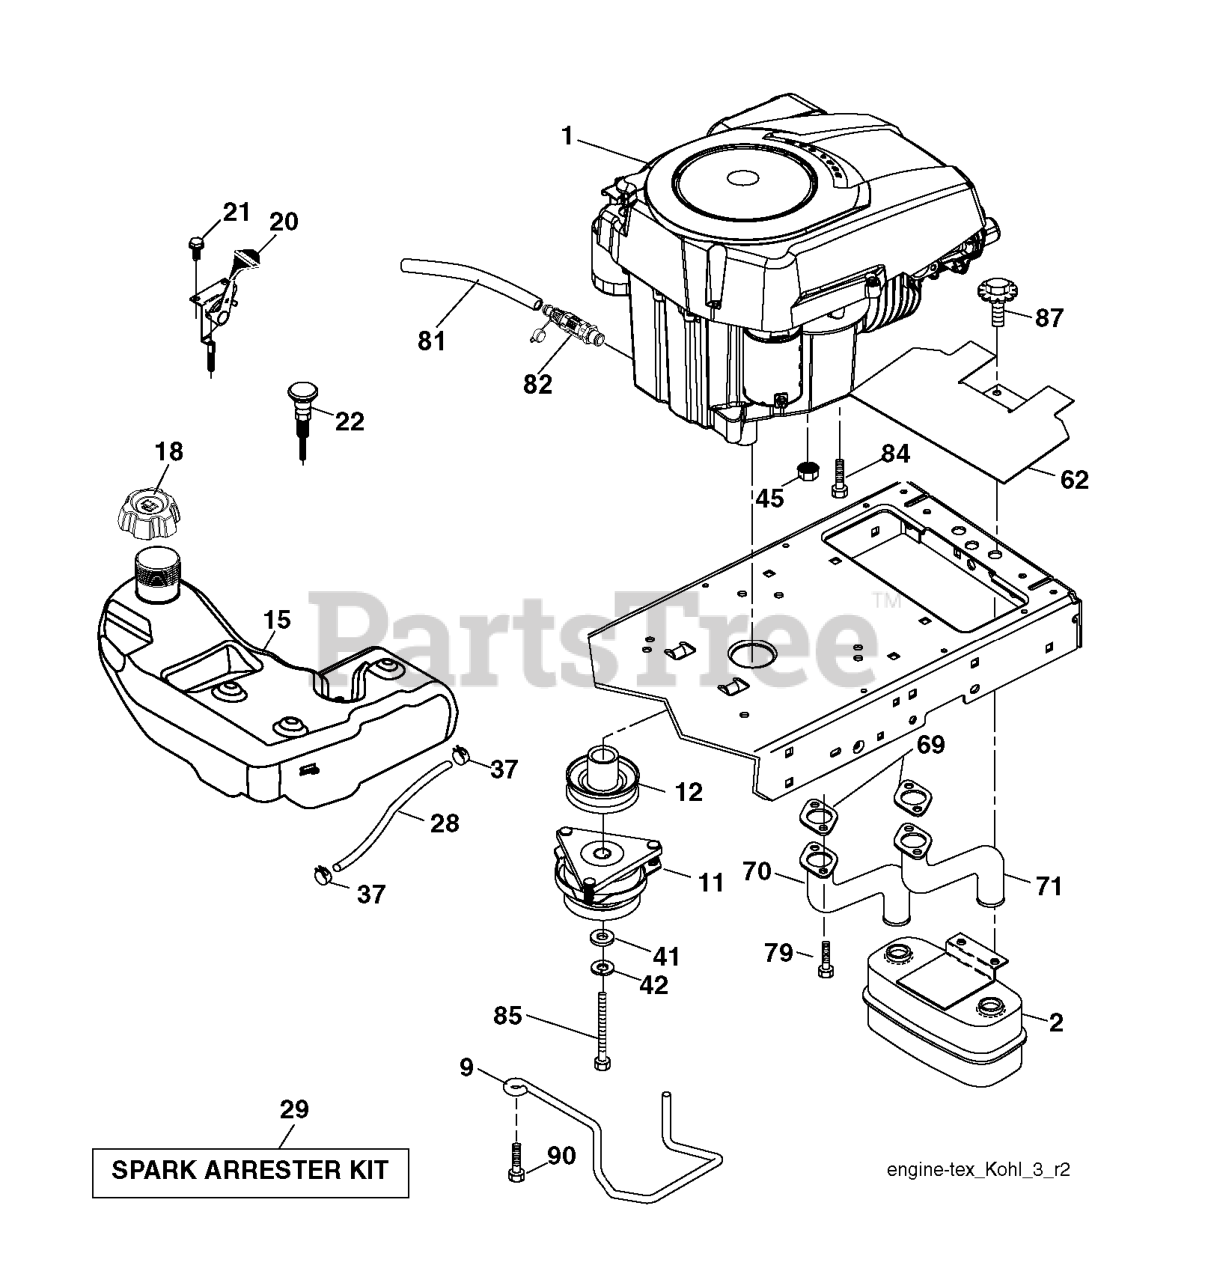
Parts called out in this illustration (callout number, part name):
2	MUFFLER.TWIN.CYL.LOW.TONE
9	KEEPER.BELT.ENGINE.4.2
11	CLUTCH MZ ZTR GT.48/54"1.125"
12	PULLEY ENGINE
15	TANK.FUEL.4GAL
18	RP CAP FUEL
20	THROTTLE CONTROL
21	SCREW.#10 X 0.750.BOS
22	CONTROL.CHOKE.ERGO.PUSH-IN.BLA
28	REPL BY 532 00 85-43
29	KIT.SPARK ARRESTOR 794945 B&S
37	HOSE CLAMP
42	LOCKWASHER
45	NUT
62	SHIELD.HEAT.MUFFLER
70	RP.PIPE-EXHAUST LH
71	RP.PIPE-EXHAUST RH
79	SCREW.SOCKET HD.5/16-1
81	TUBE, DRAIN OIL ASM.
82	VALUE.OIL.DRAIN
84	SCREW 3/8-16X1
85	BOLT HEX 7/16-20 X 3.75 GR. 5
87	BOLT.5/16-18UNCX1.W/SEMS.BLK
90	SCREW 3/8-16X1
